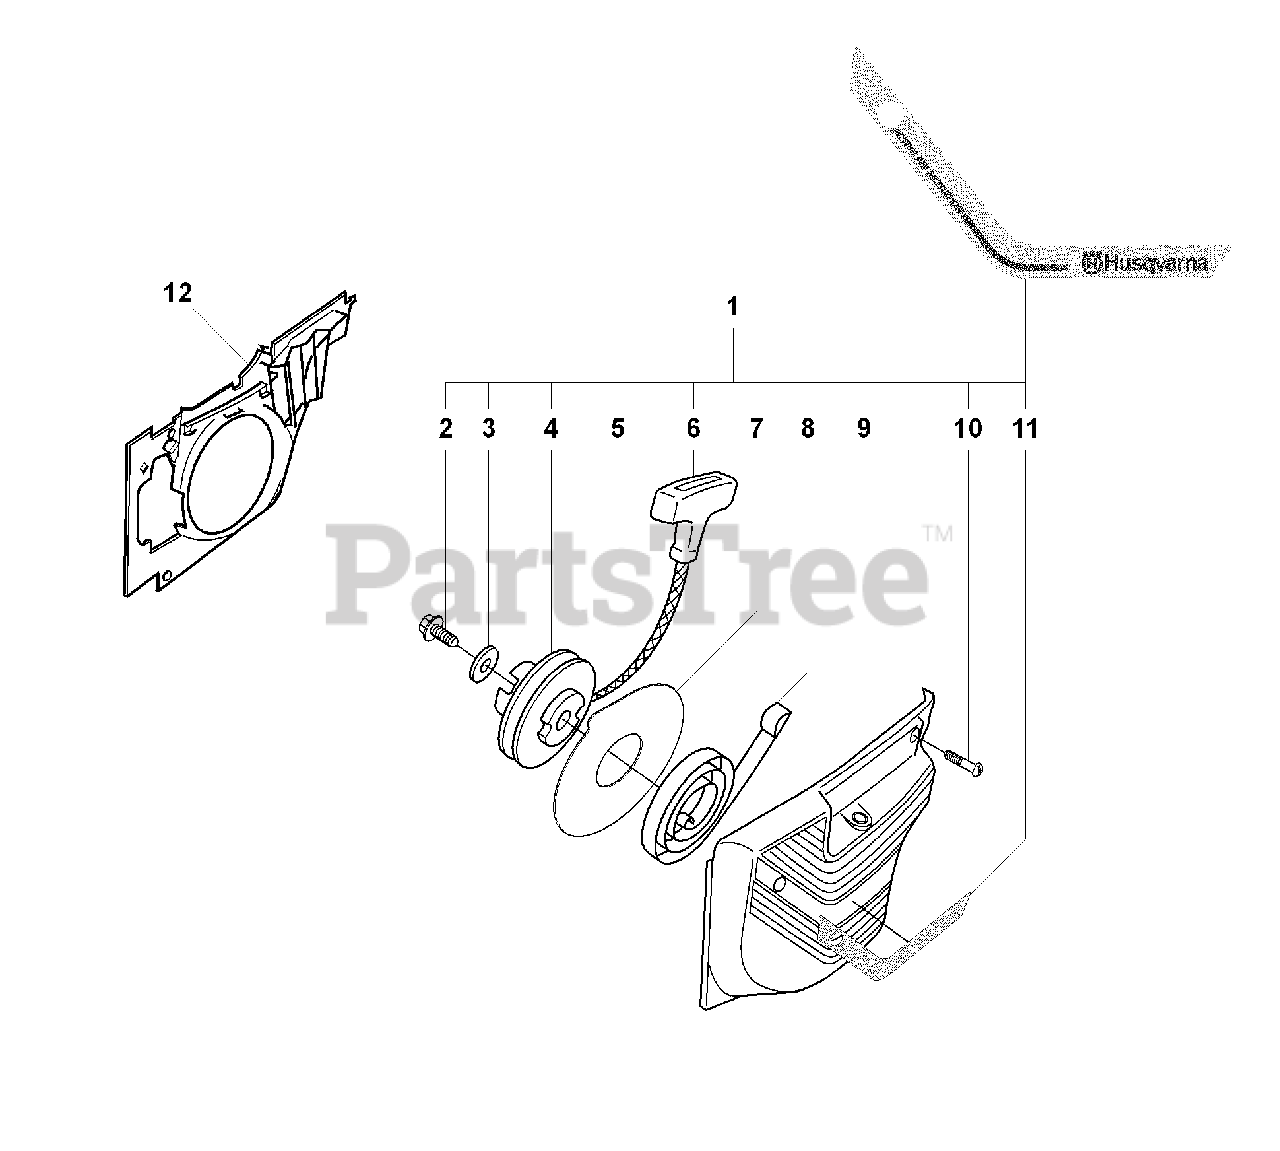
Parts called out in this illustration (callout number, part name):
1	STARTER
2	SCREW
4	STARTER PULLEY
5	STARTER CORD
6	STARTER HANDLE
8	RECOIL SPRING ASSY
9	STARTER COVER
10	SCREW
12	AIR CONDUCTOR
